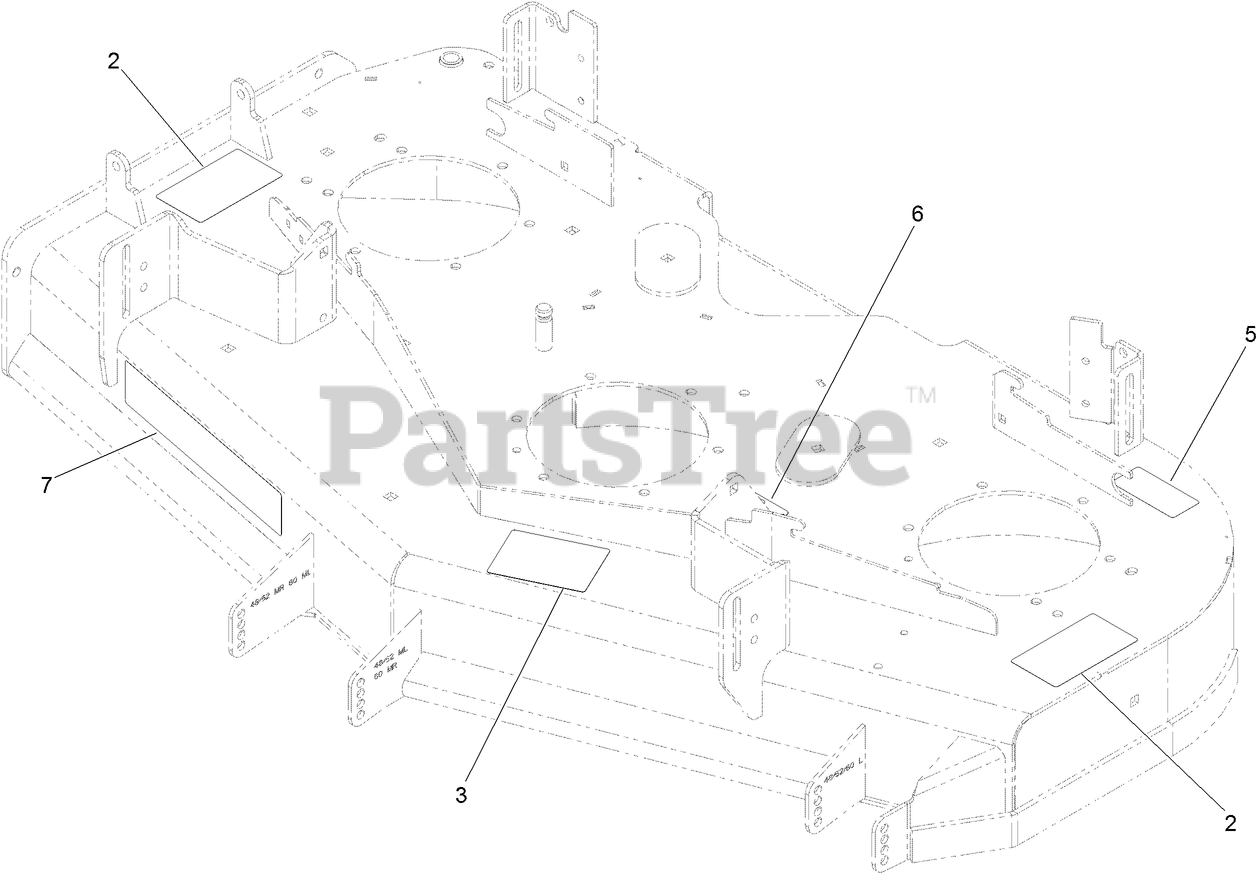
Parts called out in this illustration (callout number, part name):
2	DECAL-DANGER
3	DECAL-SCALP, ANTI
5	DECAL-BOLT TORQUE
6	DECAL-ROUTING, BELT
